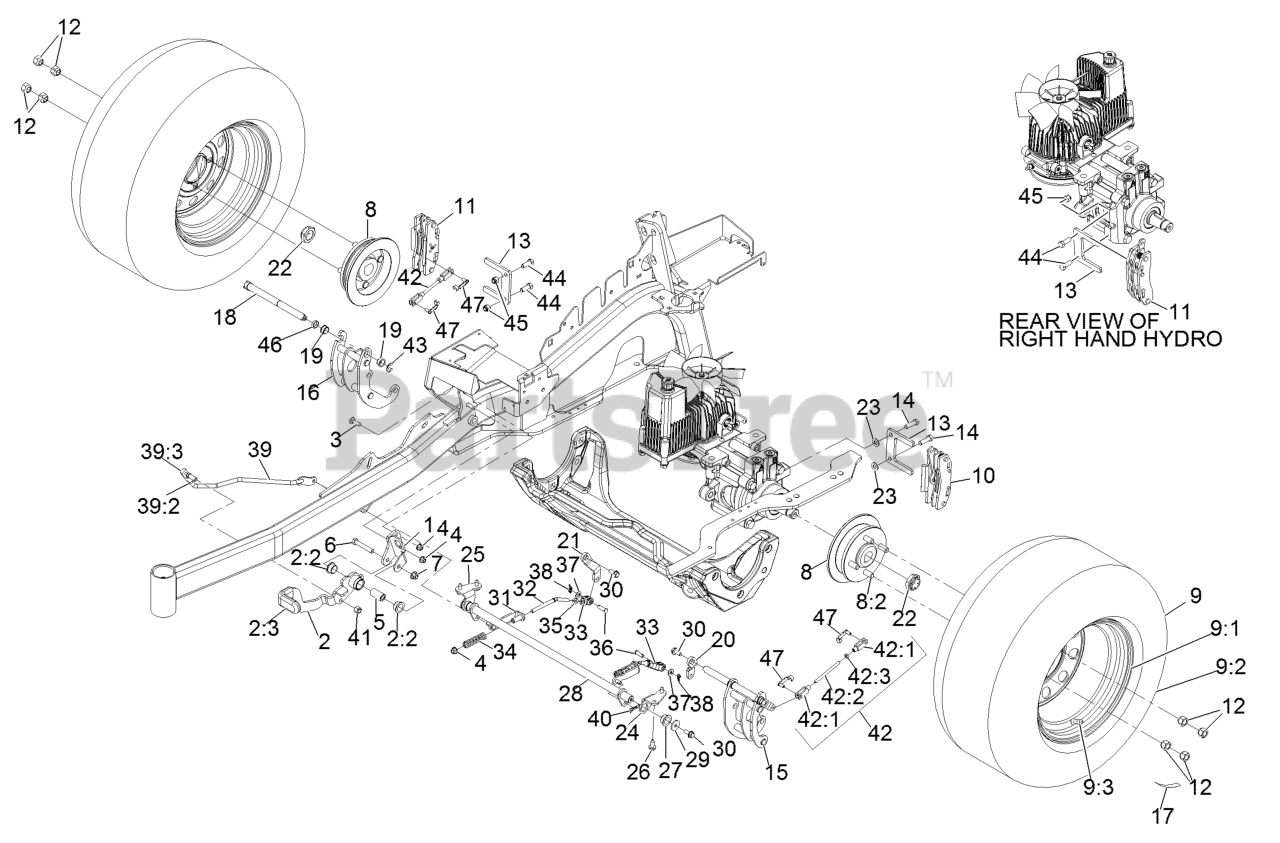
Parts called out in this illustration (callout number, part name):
1	BRACKET-MOUNT
2	BRAKE LEVER ASM W/ GRIP
2:2	BUSHING-FLANGE
2:3	GRIP-LEVER
3	BOLT-CARR
4	NUT-HF, NI
5	HANDLE-PIVOT, BRAKE
6	SCREW-HH
7	NUT-HF, NI
8	WHEEL HUB ASM
8:2	STUD-WHEEL
9	ASM-WHEEL AND TIRE
9:1	ASM-RIM 60
9:2	TIRE-DRIVE
9:3	Stem-Valve
10	CALIPER-BRAKE
11	CALIPER-BRAKE, RH
12	NUT-LUG
13	PLATE-MOUNT, BRAKE
14	SCREW-LOCK, PATCH
15	MOUNT-BELLCRANK, LH
16	MOUNT-BELLCRANK, RH
17	DECAL-TORQUE, WHEEL HUB LUG
18	BELLCRANK
19	BUSHING
20	ARM-INNER, LH
21	ARM-INNER, RH
22	LOCKNUT
23	WASHER-FLAT
24	MOUNT-PIVOT, LH
25	MOUNT-PIVOT, RH
26	Screw-HWH 5/16-18 X 3/4 Tf
27	BUSHING-FLANGE
28	SHAFT-CROSS
29	WASHER-FLAT
30	SCREW-HHF
31	BRACKET-L
32	LINKAGE-MID
33	YOKE-OFFSET
34	SPRING-COMPRESSION
35	NUT-JAM
36	PIN-CLEVIS
37	WASHER-PLAIN
38	PIN-COTTER, LOCKING
39	FRONT LINKAGE ASM
39:2	END-TIE ROD, RH
39:3	NUT-HJ
40	PIN-COTTER, LOCKING
41	NUT-LOCK
42	REAR LINKAGE ASM
42:3	NUT-JAM
44	SCREW-HH
45	NUT-LOCK, NI
47	PIN-CLEVIS, SPRING
